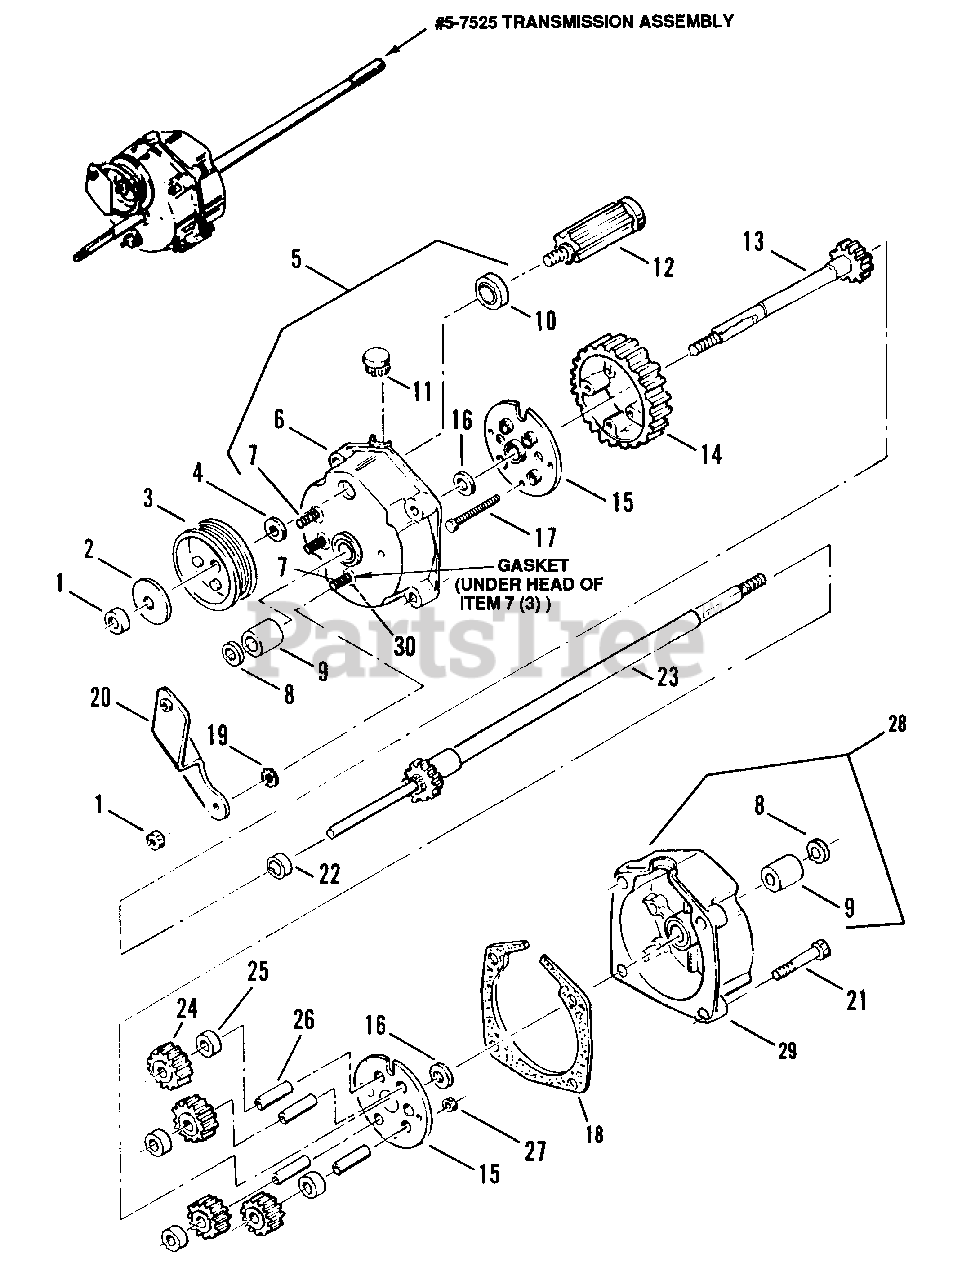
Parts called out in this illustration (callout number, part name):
1	NUT, 5/16-24 Hex Lock, Grade C
2	WASHER, Spring
3	PULLEY, Poly-V Belt
4	WASHER, Spring
5	ASSEMBLY, Right Housing
6	HOUSING, Right Side
7	SCREW, 5/16-24 x 1-1/8" Round Head Ribbed Neck
8	SEAL, 5/8" I.D.
9	BEARING, Differential
10	BEARING, Ball
11	PLUG, Housing
12	GEAR, Input
13	AXLE, Short
14	GEAR, Differential, 46 Tooth
15	PLATE
16	WASHER, Thrust
17	SCREW, #10-32 x 1-1/2" Hex Head Cap, Grade 5
18	GASKET, Housing
19	WASHER, 5/16" Internal/External Tooth Lock
20	BRACKET, Differential
21	SCREW, 1/4-20 x 1-1/4" Hex Washer Self-Tap
22	SPACER, Axle Gear
23	AXLE, Long
24	GEAR, Pinion, 12 Tooth
25	SPACER, Pinion Gear
26	SHAFT, Pinion
27	NUT, #10-32 Hex Nyloc
28	ASSEMBLY, Left Housing
29	HOUSING, Left Side
30	GASKET, 5/8" O.D.
57525	ASSEMBLY, Transmission
